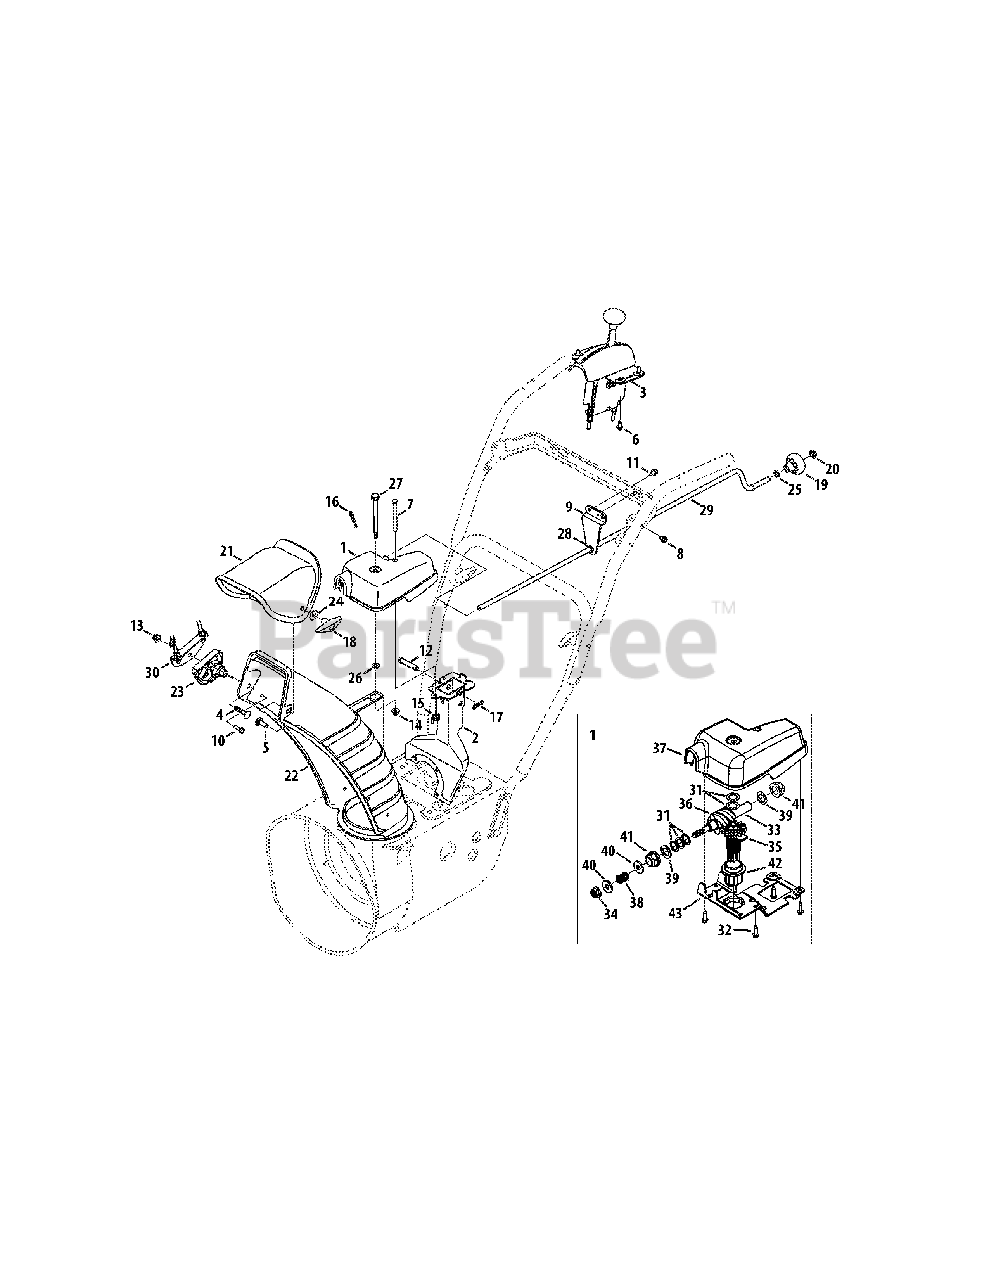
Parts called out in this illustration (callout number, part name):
1	Chute Rotation Gearbox
2	Chute Support Bracket
3	Chute Control, 2-Way
4	Bolt, Carriage, 5/16-18 x 1.50
5	Bolt, Carrier, 5/16-18 x 1.00
6	Screw, Hi-Lo, 1/4-15 x 0.50
7	Hex Head Screw, 1/4-20 x 3.00
8	Screw, TT, 1/4-20 x .500
9	Support Rod Bracket
10	Screw, Hi-Lo, 1/4-15 x 0.750
11	Screw, 1/4-20 x .625
12	Clevis Pin, 3/8 x 1.87
13	Nut, Flange Lock, 5/16-18
14	Nut, Flange Lock, 1/4-20
15	Wing Nut, 1/4-20
16	Internal Cotter Pin
17	Bow-Tie Cotter Pin
18	Wing Knob, 5/16-18
19	Shift Knob, .390
20	Push Cap, 3/8
21	Upper Chute
22	Lower Chute, 5.0
23	Cable Guide, Chute Tilt
24	Washer, Flat, .349 x .879
25	Flat Washer, .375 x .738 x .063
26	Washer, Flat, .25 x .630
27	Shoulder Screw, .312 x 3.5 x 1/4-20
28	Plastic Bushing, .380 ID
29	Chute Crank
30	Cable Bracket
31	Shim Washer, .632 x 1.00 x .010
32	Screw, 12-16 x .75
33	Worm Shaft
34	Flange Lock Nut, 3/8-16
35	Gear Assembly
36	Worm
37	Gear Cover
38	Compression Spring, .39 x .60 x .88
39	Flat Washer, .625 x 1.0 x .067
40	Flat Washer, .380 x .93 x .110
41	Hex Bearing
42	Flange Bearing
43	Gear Bracket
